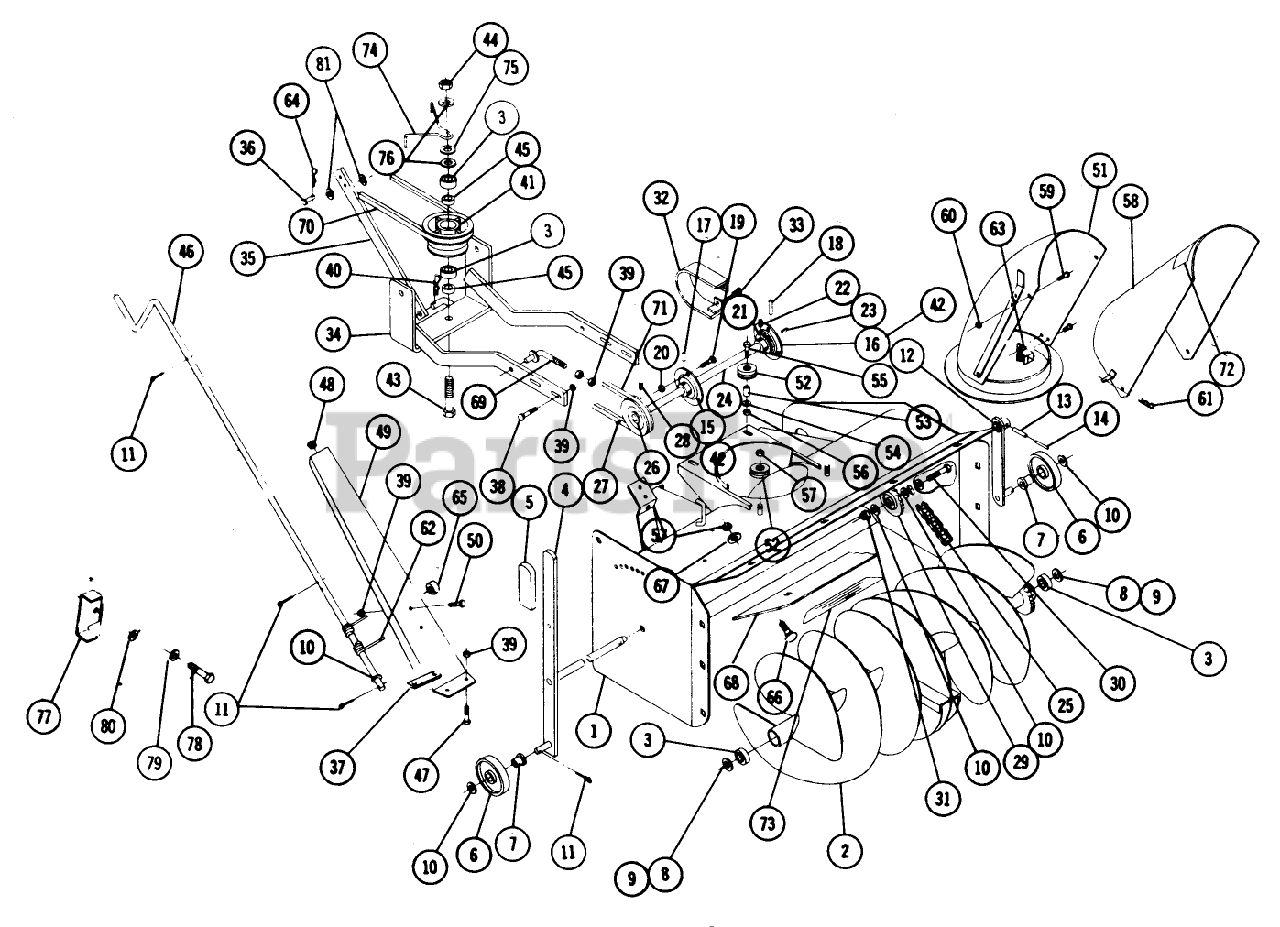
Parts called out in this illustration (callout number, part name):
3	BEARING-BALL
5	GRIP
8	Washer .080
9	WASHER
10	Washer
11	Cotter Pin
13	ROLL PIN 1/4 X 1-1/4
14	PIN-SPIROL
17	Set Screw
18	PIN-ROLL, SPIROL
19	Bolt Hex 5/16-18 x 3/4
20	Nut-Nylok
22	Set Screw Nylok
23	Key
27	KEY-HI-PRO
28	Set Screw
30	Bolt-1/2-13-1 3/4
31	Locknut-1/2-13
34	Mounting Frame
35	Ass-y.-Lift Link
36	Pin-Clevis 1/2 x 1 1/2
38	Bolt Carriage 3/8-16 x 1
40	Hairpen
41	Idler Pulley
42	FLANGE
43	Bolt-Hex 3/4-10 x 3 1/2
45	Spacer
48	NYLINER BUSHING
49	Support-Crank
50	Bolt Hex 3/8 16 x 1/2
54	Washer
55	Bolt 1/4 20 x 1 1/4
56	Nut-Nylok
57	3/8-16 E.S.
59	Bolt Pan Head 1/4-20 x 1/2
60	Nut, 1/4-20
61	Hairpin
63	CLAMP
64	Hairpin
65	Bushing
66	Bolt 3/8-16 x 1
67	Washer
70	BELT DRIVE
72	Decal-Caution
74	Belt Guide
75	Washer
76	Washer
78	Bolt-Hex 3/8-16 x 2
79	Washer
80	Washer
81	Washer-Flat
